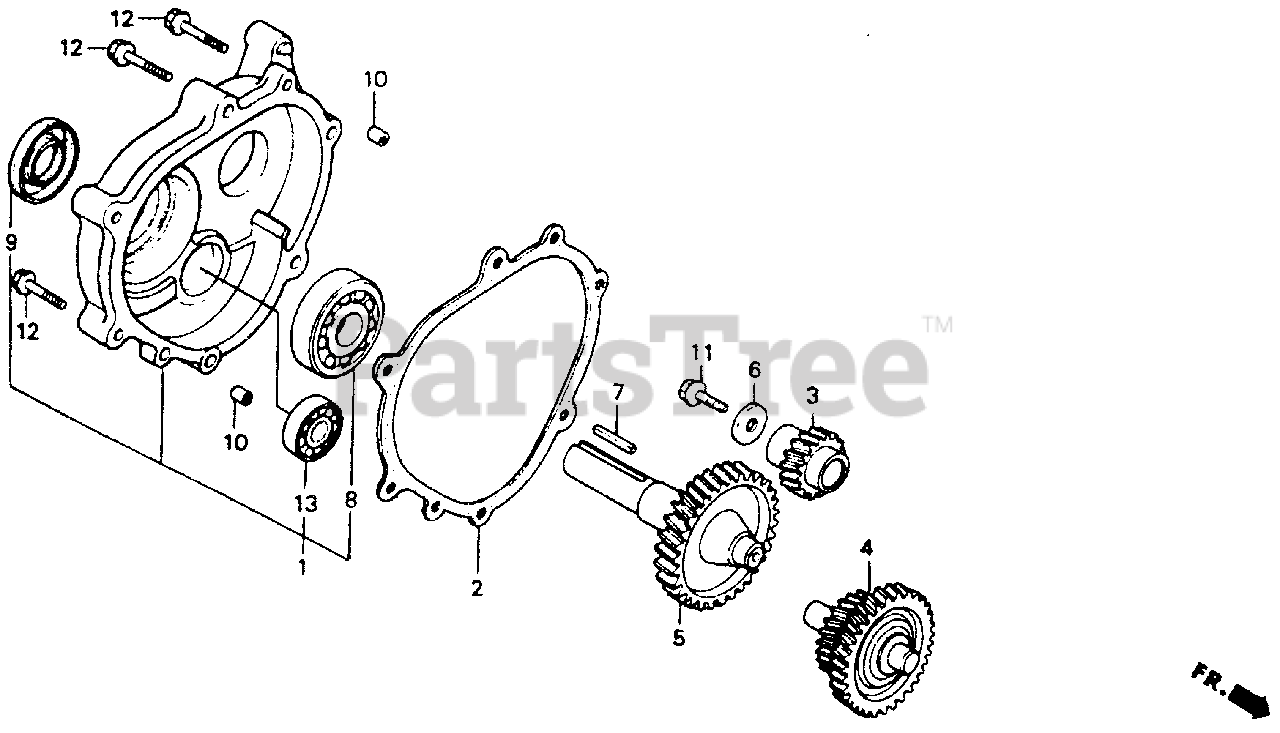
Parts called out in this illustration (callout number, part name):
1	COVER ASSY., GEAR CASE (H-TYPE)
2	GASKET, CHAIN CASE COVER
3	GEAR, PRIMARY DRIVE (12T)
4	COUNTERSHAFT
5	SHAFT, P.T.O. (H-TYPE)
6	WASHER (8MM)
7	KEY (6.3X6.3X43)
8	BEARING, RADIAL BALL (6206) (NTN CORP.)
9	OIL SEAL (30X46X8)
10	PIN A, DOWEL (8X14)
11	BOLT, FLANGE (8X25)
12	BOLT, FLANGE (8X40)
13	BEARING, RADIAL BALL (6302)
